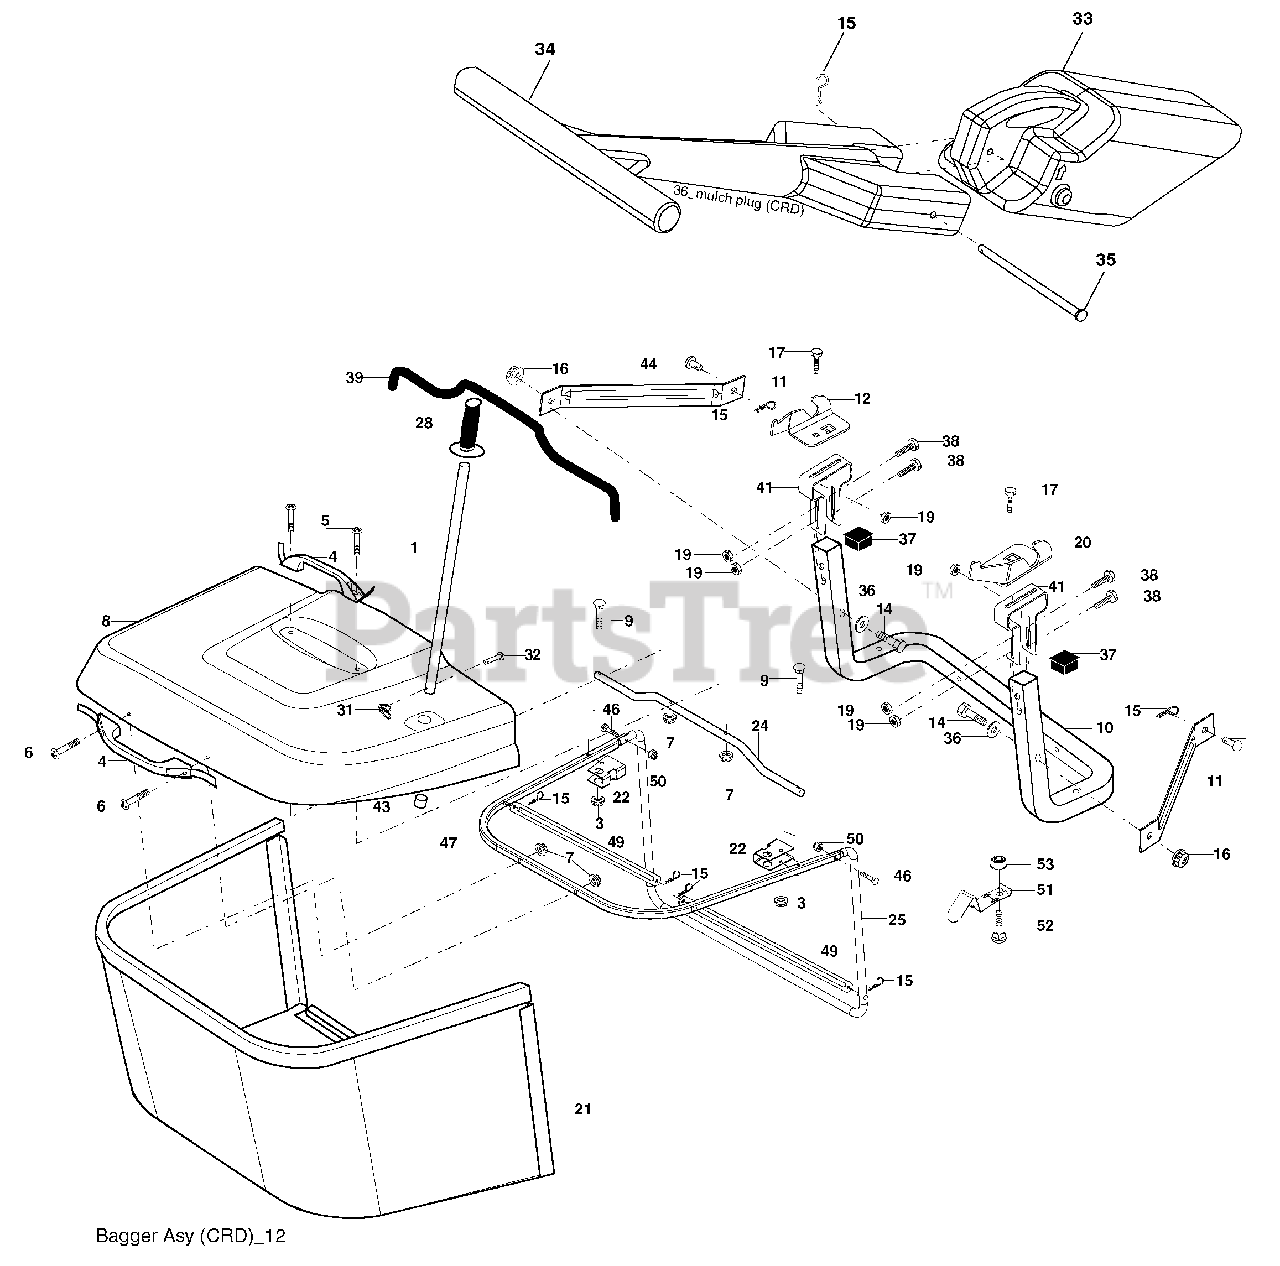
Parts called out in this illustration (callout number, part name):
1	Tube Handle Bagger CRD
3	Nut Lock 1/4 Lge Flg Gr. 5 Zinc
4	Handle Bagger w/Lvrs Blk CRD
5	Screw Pan Head #10-24 x 1.50
6	Screw Pan Hd
7	Nut Wiz Lock Hex Serr/Hd 10-24
9	Bolt Carr. 1/4-20 x 2.25d x Gr. 5
10	Tube Support Bagger CRD
11	Bracket Support Upper Bag CRD
12	Bracket Pivot LH
14	Bolt RDHD SQNK 3/8-16 x 2-1/4 Gr. 5
15	Retainer Spring
16	Nut Lock Flg 3/8-16 unc
17	Bolt Rdhd Sht Sqnk 5/16 -18 unc x 3/4
19	Nut Lock Hex Flange 5/16-18
20	Bracket Pivot RH
22	Bracket Side Bagger CRD
24	Tube Pivot Bagger CRD
25	Tube Front Bagger CRD
31	Retainer Clip
32	Rivet Rd Hd Drilled 3/8 Dia.
33	Plug Mulcher
34	Handle Mulcher
35	Pin Mulcher
36	Washer 13/32 x 1-1/4 x 12 Ga.
37	Plug Support Bagger CRD
38	Bolt 5/16-18 x 2-1/2
39	Seal
41	Bracket Pnt Adj Pvt Bagger CRD
43	Plug Tubing End
44	Pin Clevis 3/8 x 11/16
46	Bolt carr 5/16-18 x 1-1/4 Gr. 5
47	Tube Upper
49	Bar Spreader
50	Nut Lock Hx W/Insert 5/16-18 unc
51	Latch Spring
52	Bolt Rdhd Sqnk 1/4-20 x 3/4 Gr. 5
53	Nut Keps Hex 1/4-20 unc
